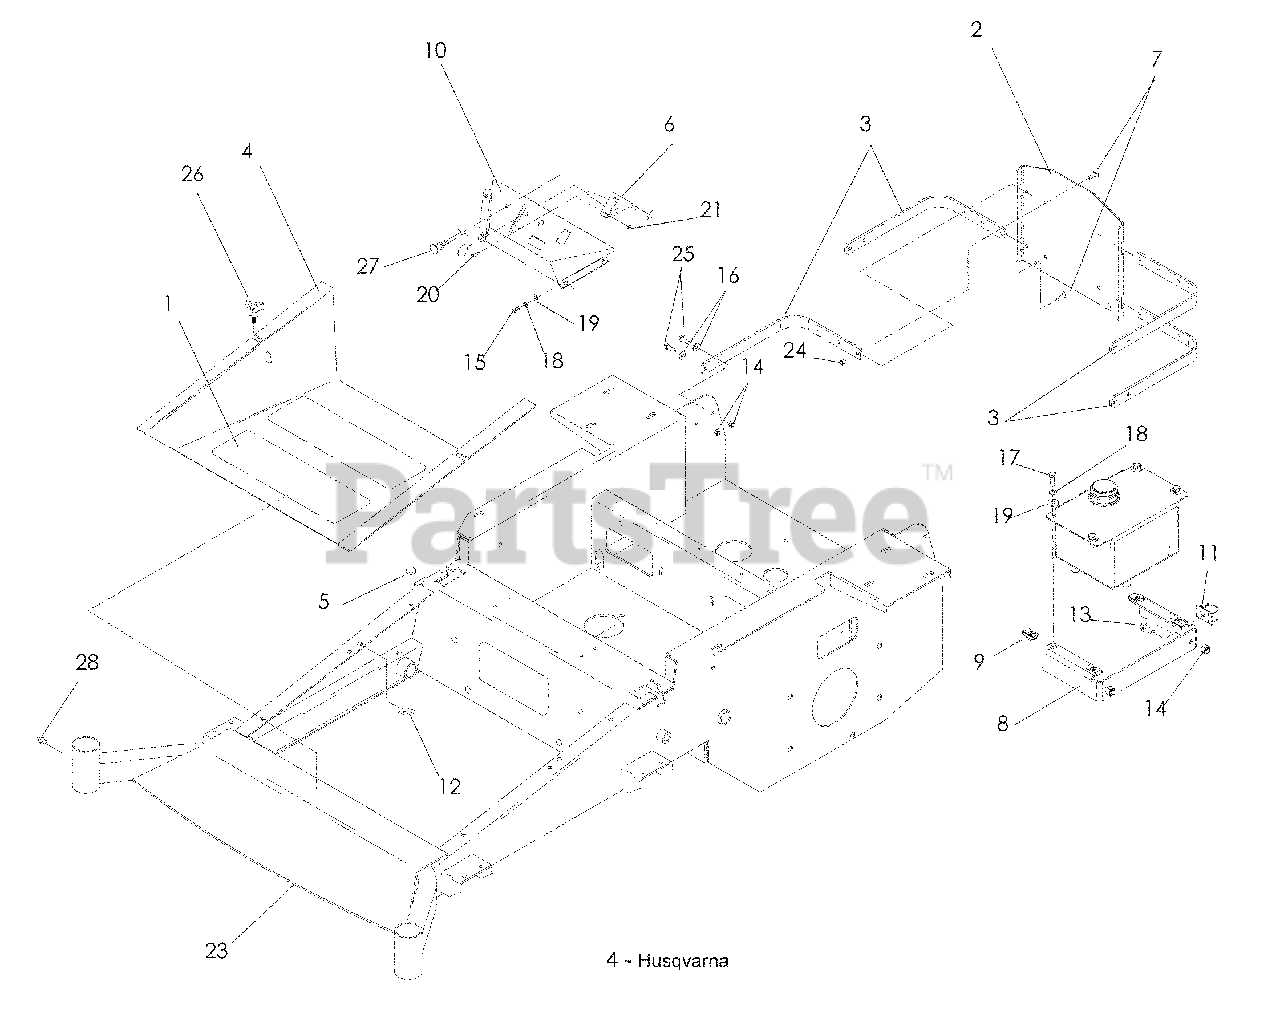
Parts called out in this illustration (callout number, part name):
1	FLOOR PAN PAD
2	XP GUARD, BLACK
3	STRAP, BLACK
4	FOOT PLATE
6	CABLE, THROTTLE
7	RHSNB 5/16-18 x ¾
8	TANK MOUNT
9	U TYPE RETAINER
11	CLIP, PUSH MOUNT
12	U CLIP 5/16-18
13	HCS 5/16-18 x ¾
14	NUT 5/16-18 HEX NYLOC
15	TFS ¼-20 x 5/8
16	WASHER 5/16 STD FLT
17	HCS ¼-20 x ¾
18	LOCKWASHER ¼
19	WASHER ¼ FLAT
20	HCS 10-24 x ½
21	NUT 10-24 NYLOC
22	WASHER 5/16 LOCK
24	NUT 5/16-18 CENTERLOCK
25	HCS 5/16-18 x 1
26	KNOB W/STUD
27	CHOKE CONTROL
